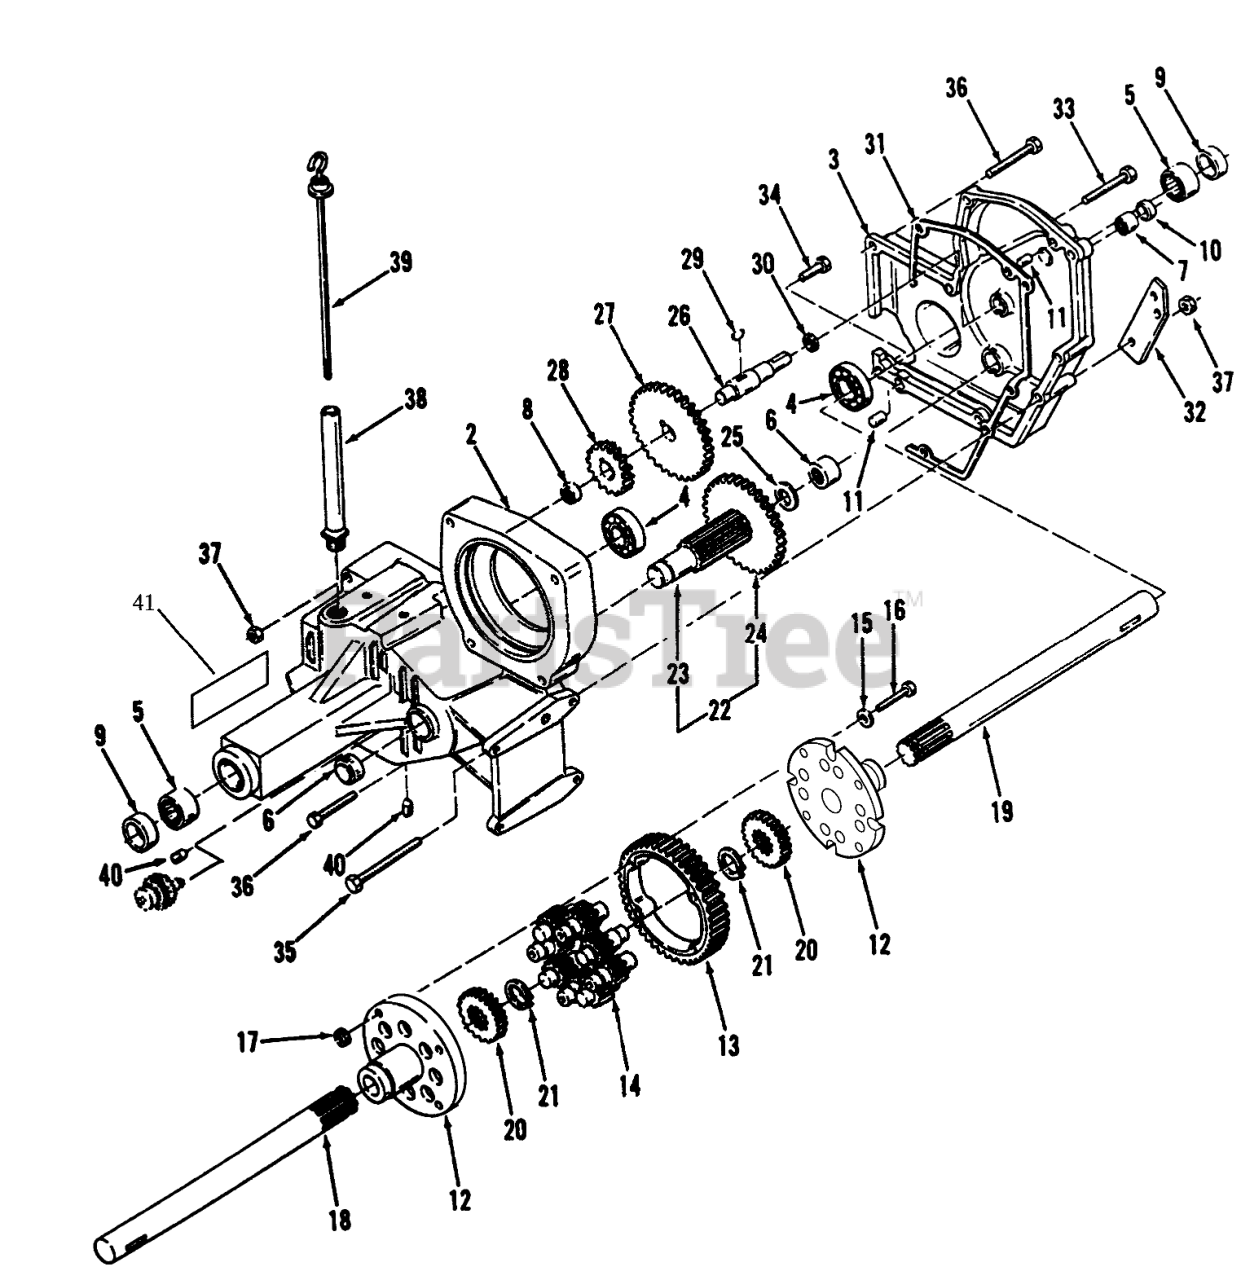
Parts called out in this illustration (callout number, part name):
1	Transaxle (Incl Ref. #41)
2	CASE-TRANSMISSION RH
3	CASE TRANS LH
4	BEARING-BALL
5	BEARING
6	BEARING-NEEDLE
7	NEEDLE BEARING
8	BEARING-NEEDLE
9	SEAL-OIL
10	Seal
11	PIN-LOCATING
12	END CAP-DIFFERENTIAL
13	GEAR-DIFFERENTIAL RING, 43T
14	GEAR-PINION, 11T
15	WASHER
16	BOLT-HEX
18	AXLE-REAR RH
19	AXLE-REAR LH
20	GEAR-AXLE DIFFERENTIAL
21	RING-SNAP
22	ASSY GEAR
23	PINION SHAFT
25	WASHER-THRUST
26	SHAFT GEAR
27	GEAR 46T
28	GEAR 20 TEETH
29	Key
30	Race Thrust
31	GASKET-TRANSMISSION
32	BRACKET-BRAKEB
34	SCREW-HH
35	SCREW-HH
36	SCREW-HH
37	NUT-LOCK, NI
38	NIPPLE-TRANS FILL
39	Dipstick
41	DECAL - DANGER
